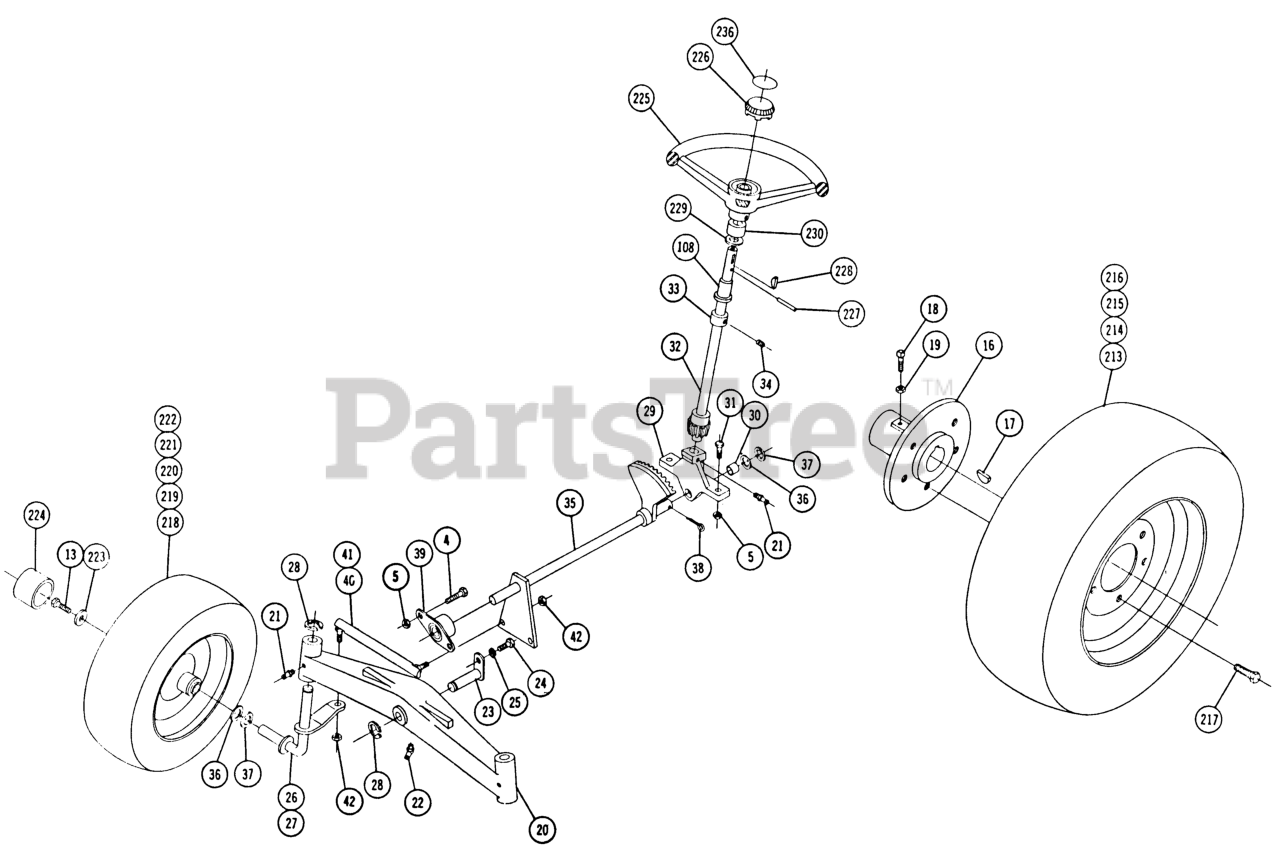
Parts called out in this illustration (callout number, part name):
1	Ass-y.Frame
2	Hoodstand
3	Cover-Dust
4	Bolt 3/8-16 x 1
5	3/8-16 E.S.
6	Bolt 5/16-18 x
7	Nut-Nylok
8	Pulley
9	Set Screw
10	WOODRUFF KEY
11	Bolt 3/8-16 x 7/8
12	Lockwasher
13	Bolt 3/8-16 x 7/8
14	Tool Box
15	Bolt 3/8-16 x 3/4
16	Hub-Wheel
17	WOODRUFF KEY
18	Screw-Set
19	3/8-16 Jam Nut
20	AXLE-FRONT
21	Zerk
22	FITTING-GREASE
23	PIN AND PLATE ASM
24	Bolt Hex 5/16-18
25	Lockwasher
26	R.H. Spindle
27	L.H. Spindle
28	E-RING
29	Support
30	BEARING-BRONZE
31	Bolt 3/8-16 x 1
32	ASSY UPPER STEER R
33	Collar
34	Set Screw 1/4-20 x 1/4 Nylok
35	Assy-Steering
36	WASHER-SHIM
37	WASHER
38	Cotter Pin
39	BEARING-FLANGED
40	Tie Rod-R.H.
41	Ball Joint L H
42	Locknut 3/8-24
43	Pedal
44	BUSHING
45	Gasket
46	Hairpin
47	Hairpin
48	Roll Pin
49	Collar
50	Lift Lever
51	LOWER PLUNGER R
52	PLUNGER ROD
53	Roll Pin
54	SPRING-COMPRESSION
55	Guide-Rod
56	Cap
57	Grip
58	Hairpen
59	Quadrant
60	ROD-LIFT CONTROL
61	KNOB-LIFT CONTROL
62	Conduit
63	Hitch
64	Pin
65	RING-SNAP, EXTERNAL
66	SPACER
67	BATTERY BOX ASSY R (NS)
68	LINK BATTERY CLAMP
69	Nut 1/4-20 Nylok
70	ever Brake
71	Washer
72	E Ring
73	Idler Arm
74	BUSHING-FLANGED
75	Bolt Hex 1/4-20 x 3/4
76	Nut-Jam 1
77	Lockwasher
78	Handle-Brake
79	KNOB
80	Washer
81	SPRING-BRAKE
82	Idler Pulley
83	SPACER-BRAKE LINK
84	Bolt 3/8-16 x 1 5/8
85	Cam Control Arm
86	Indicator-Speed
87	Bolt, 1/4-x 1/2
88	Bearing
89	PIN
91	Cam Pivot Rod
92	FRICTION COLLAR
93	COLLAR BRKT PIVOT
94	FRICTION CONE
95	SPRING FRICTION
96	Collar Friction
97	Nut 3/1-10 Jam
98	WOODRUFF KEY
99	Cam Plate
100	Spacer
101	NYLINER BUSHING
102	SHIM-WASHER
103	Spring
104	Housing
105	Support-Fuel Tank
106	Bolt Hex 5/16-18
107	Bolt 1/4-20 x 5/8 Whizlock
108	Bushing
109	Grommet
110	Panel
111	Plug Button
112	SPEED NUT
113	Screw-Self #10 10-16
114	Fuel Tank
115	Clamp-Tank
116	Cap
118	Nut Square
119	S/A FUEL VALVE
120	Hose
121	Clip
122	Fuel Hose
123	SPACER
124	CLAMP CORBIN 7/16
125	Nut 5/16-18
126	Engine 12 H.P.
127	Bolt, 3/8-16 x 1/2
128	V BELT
129	ELBOW-STREET
130	Cap
131	Nipple
132	MUFFLER
133	Nipple 1" Pipe x 2"
134	Nipple 1 Close Pipe
135	Elbow 1" x 45
136	PULLEY
137	Key
138	Control Choke
139	Control Throttle
140	Lockwasher 9/16
141	RING NUT
142	SWITCH
143	Nut
144	Lockwasher 6/16
145	Insulator
146	Key-EL
147	Cigar Lighter
148	Knob & Plug
149	SHELL CLAMP
150	Socket
151	Nut #8-32
152	LOCKWASHER
153	Wire
154	Battery
155	Ground Wire
156	Harness-Wiring
157	ASSY REFLECTOR HOUSI
158	WIRE ASSY
159	SPRING
160	BULB
161	Lens
162	Pan HD Swage
163	Switch
164	Harness
165	SPEED CLIP
166	CONNECTOR 3 WIRE
167	CLIP-WIRE
168	Tail Light
169	Base
170	Lens
171	Bulb
172	CONNECTOR 2 WIRE
173	Bolt #10-32
174	Nut Hex #10-32
175	Lockwasher #10
176	Mounting Pad
177	Belt Guard
178	Bolt Hex 7/16-4 x 3/4
179	Lockwasher 3/8
180	Bracket
181	Bolt, 5/16-18 x 1/2
182	Footrest R.H.
183	Footrest L.H.
184	BRACKET
185	Bolt-Carriage 5/16-18
186	Latch Fender
187	Spring
188	NYLINER BUSHING
189	Pin
190	BRACKET FENDER LATCH
191	Nut 1/4-20 Elastic Stop
192	Cover Plate
193	Bolt, 1/4-20 Whizlock
194	Fender
195	SPACER
196	GROMMET
197	Seat
198	Washer
199	Ass-y Hood
200	Hood-Hinge
201	NYLINER BUSHING
202	Rod Pivot
203	LEVER HOOD LATCH
204	KNOB
205	SPIROL PIN
206	Roller Rubber
207	Roller
208	Nut-Hi Crown
209	SPEED NUT
210	Rod Latch
211	Hood Ornament
212	SPEED NUT
213	Wheel and Tire
214	Wheel
215	Tire
216	VALVE TUBELESS
217	Lug Nut
218	Wheel, Tire & Tube
219	Tire
220	Bearing
221	Tire
222	Tube
223	WASHER
224	Hub Cap
225	Steering
226	CAP INSERT
227	ROLL PIN 1/4 X 1-1/4
228	Key
229	WASHER-BOWED
230	COLLAR
231	Decal-"6"
232	Decal "12"
233	Clip, Push-on
234	Decal Hood Trim L.H.
235	Decal
236	Decal
237	Decal Free Wheeling
238	Decal
239	Pin-Tool
240	Special Nut
241	Clip
242	Bolt 1/4-20 x 3/8
